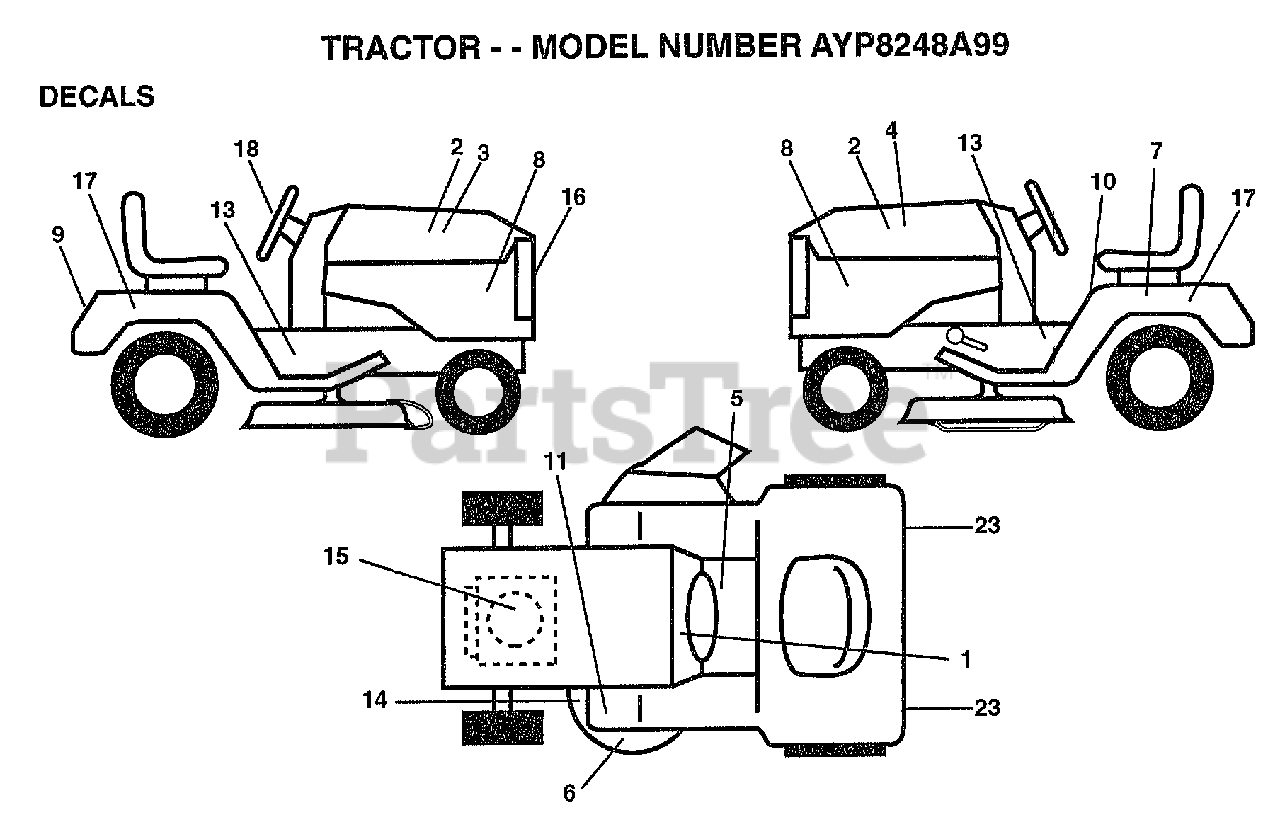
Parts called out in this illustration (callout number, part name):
1	"DECAL-INST,OPER"
2	NAMEPLATE.HD.WIZA
3	DECAL.HOOD.RH
4	DECAL.HOOD.LH
5	DECAL BRAK PARK
6	DECAL DECK WIZ +
7	DECAL.BATRY.3-3908
8	DECAL, PNL SIDE
10	"DECAL DANGER,FEND"
13	DECAL CHASSIS 50
16	DECAL.GRILLE.WIZ+
17	DECAL.FENDER.WIZ
18	DECAL INS STG WHL
23	REFLECTOR-TAIL YT
